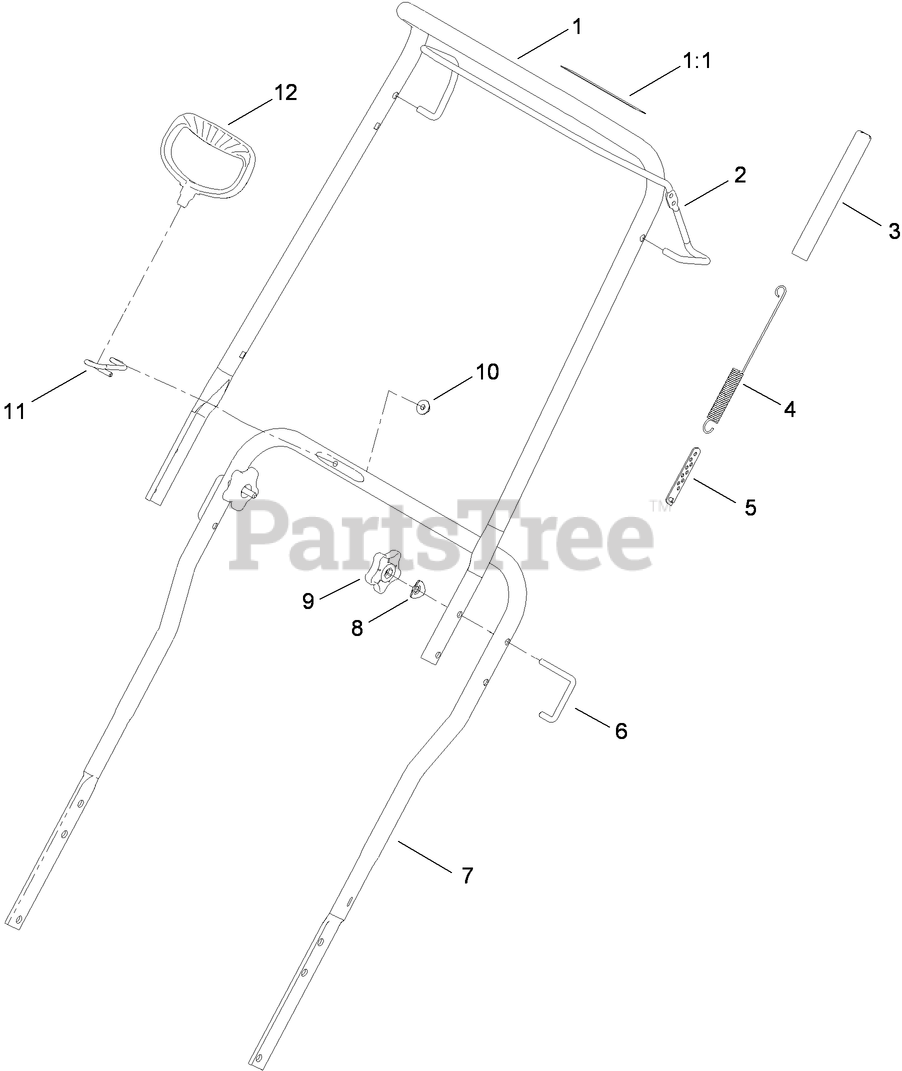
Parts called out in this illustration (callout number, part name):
1	UPPER HANDLE ASM
1:1	DECAL-DRIVE, ROTOR
2	BAIL-CONTROL
3	COVER-SPRING
4	SPRING-EXTENSION
7	HANDLE-LOWER
8	WASHER
9	KNOB-HANDLE
10	NUT-HF
11	GUIDE-ROPE
12	HANDLE-RECOIL
